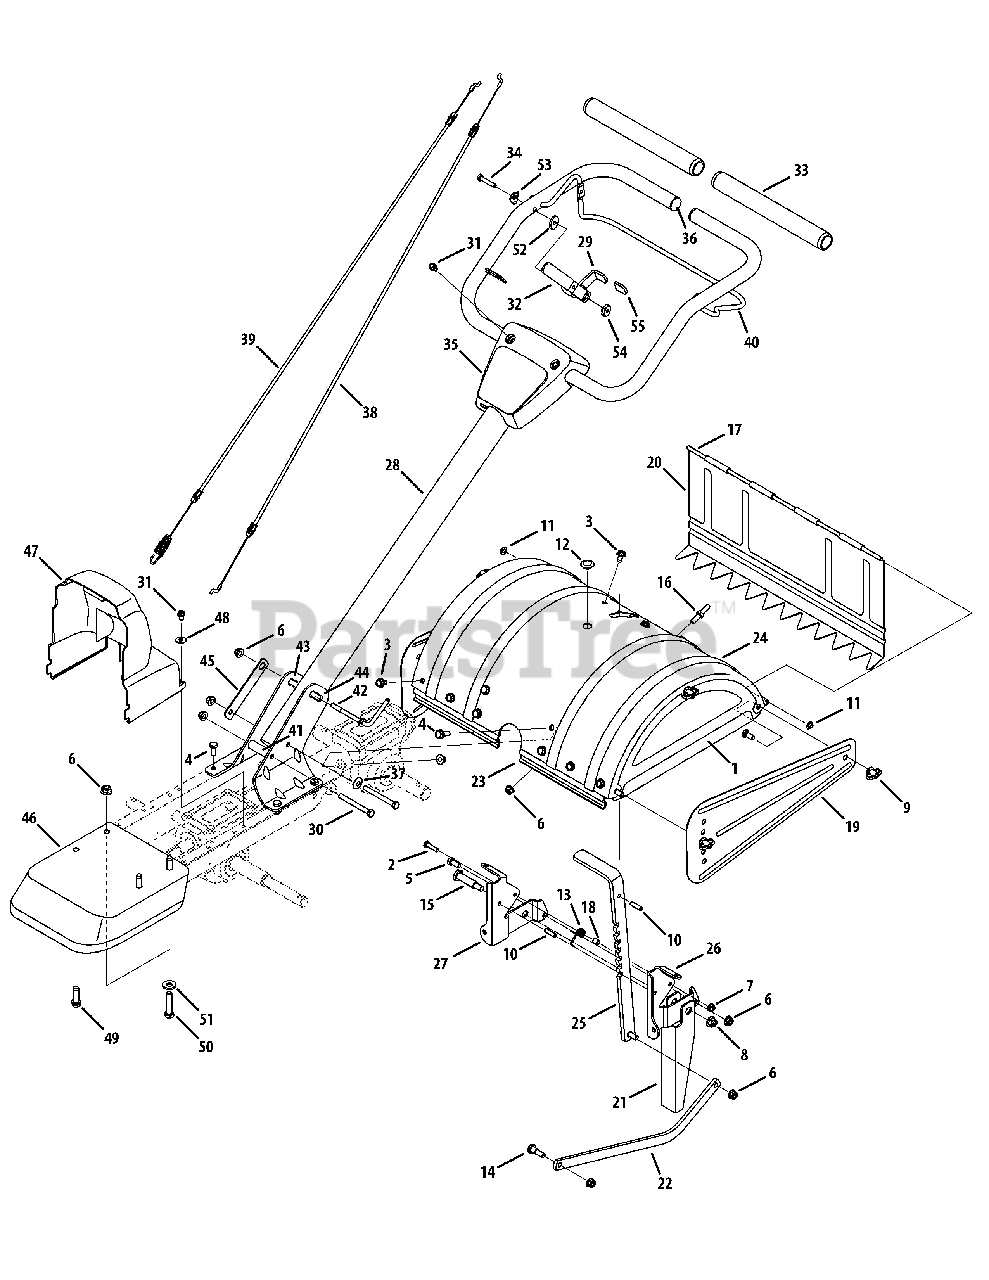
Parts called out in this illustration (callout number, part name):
1	End Cover Assembly
2	Hex Head Screw, 1/4-20 x 1
3	Hex Head Screw, 5/16-18 x .625
4	Hex Head Screw, 5/16-18 x .875
5	Hex Head Screw, 5/16-18 x .75
6	Nylon Hex Lock Nut, 5/16-18
7	Nylon Hex Lock Nut, 1/4-20
8	Flange Lock Nut, 3/8-16
9	Wing Nut, 5/16-18
10	Spirol Pin
11	Cap Nut, 1/4 Rod
12	Hole Plug
13	Torsion Spring
14	Shoulder Screw, .405 x .435 5/16-18
15	Shoulder Screw, .498 x 1.635
16	Stop Screw
17	Tiller Flap Rod
18	Spacer
19	Side Shield
20	Rear Tine Shield
21	Reverse Stop Arm
23	Tine Shield Mounting Bracket
24	Tine Shield
25	Adjustable Depth Bar
26	Tail Bracket, LH
27	Tail Bracket, RH
28	Upper Handle Assembly
29	Reverse Handle Assembly
30	Hex Head Screw, 5/16-18 x 3.00
31	Self-Tapping Screw, 1/4-20 x 1/2
32	Handle Select
33	Foam Handle Grip
34	Hex Head Screw, 1/4-20 x 1.62
35	Handle Cover
36	Plug End
37	Bell Washer, .340 x .872 x .060
38	Reverse Cable
39	Forward Cable
40	Clutch Bail
41	Spacer, .322 x .625 x 2.00
42	Handle Crank
43	Handle Bracket, RH
44	Handle Bracket, LH
45	Retainer Nut Bracket
46	Front Bumper
47	Belt Cover
48	Flat Washer, .28 x .74 x .063
49	SEMS Screw, 3/8-16
50	Hex Head Screw, 5/16-18 x 1.50
51	Bell Washer, .827 x .331 x .098
52	Flat Washer, .265 x .938 x .120
53	Saddle Washer, .320 x .930 x .060
54	Spacer, .375 x .165
55	Reverse Handle Grip
